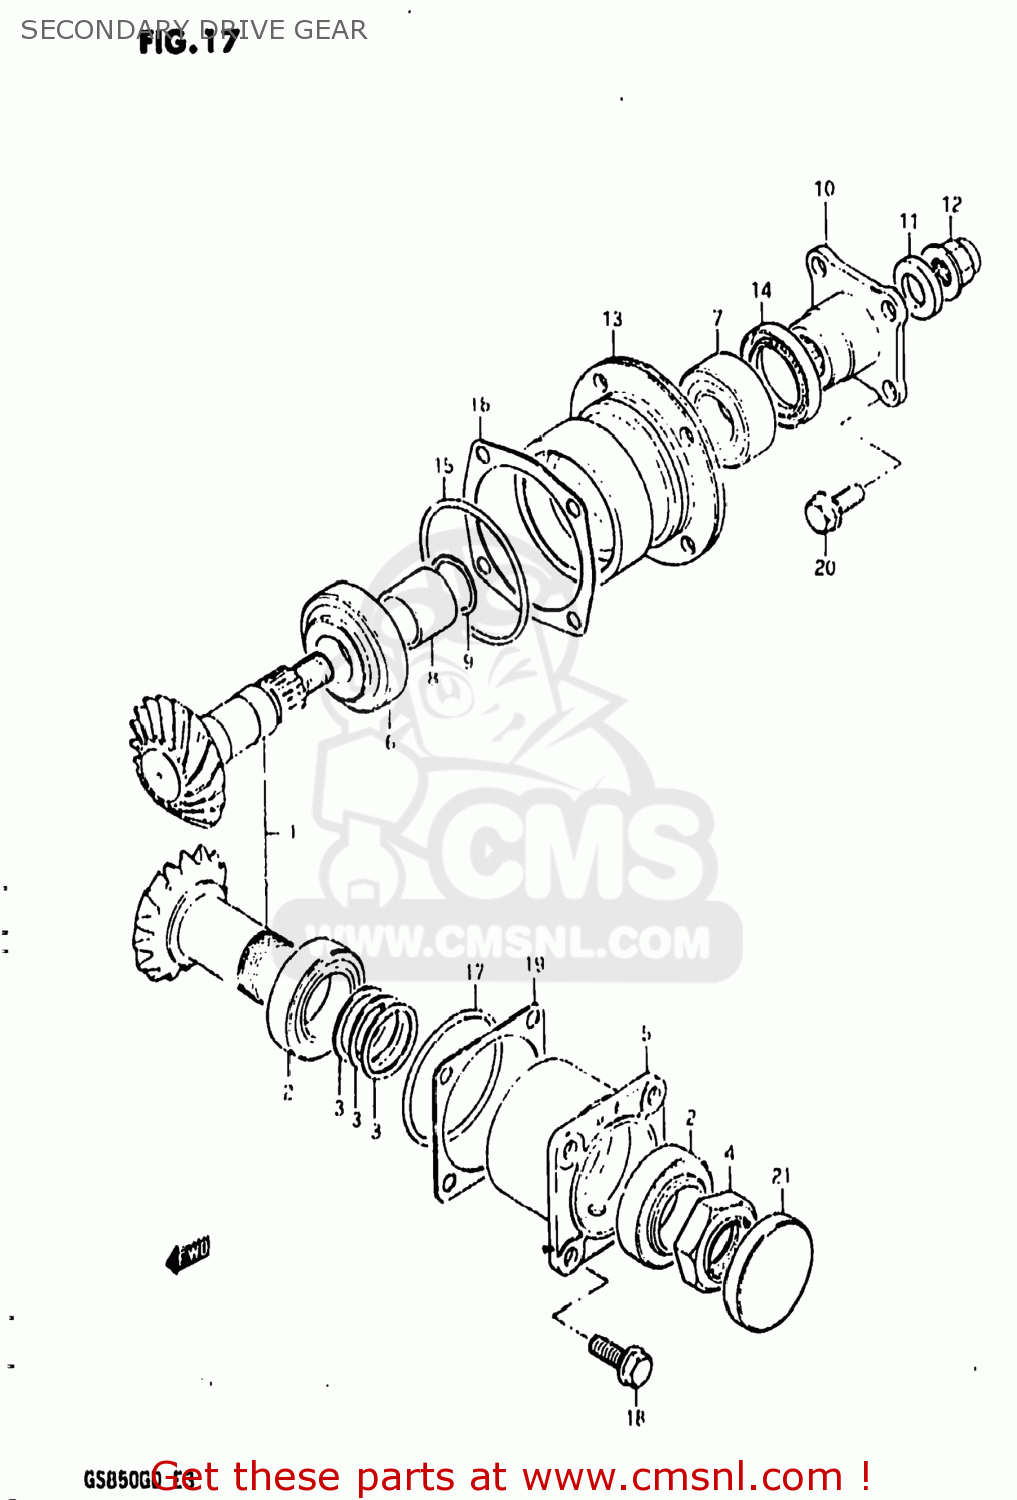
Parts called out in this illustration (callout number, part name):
1	GEAR SET,SECON
2	BEARING(32X58X17)
3	SHIM(32X38X2)
4	NUT
5	HOUSING,SECONDARY DRIVE
6	TAPER,ROLLER BEARING
7	BEARING
8	SPACER (25.2X30X40)
9	SHIM (25X30X2
10	FLANGE,UNIVERSAL JOINT
11	WASHER(14X29X4)
12	NUT
13	HOUSING,SECONDARY DRIVE
14	SEAL,OIL(35X52X9)
15	O RING(D:3.1,ID:69.4)
16	SHIM,DRIVEN GEAR HOUSING
17	O RING(D:2.4,ID:62.6)
18	BOLT
19	SHIM,SECONDARY DRIVE
20	BOLT
21	PLUG
